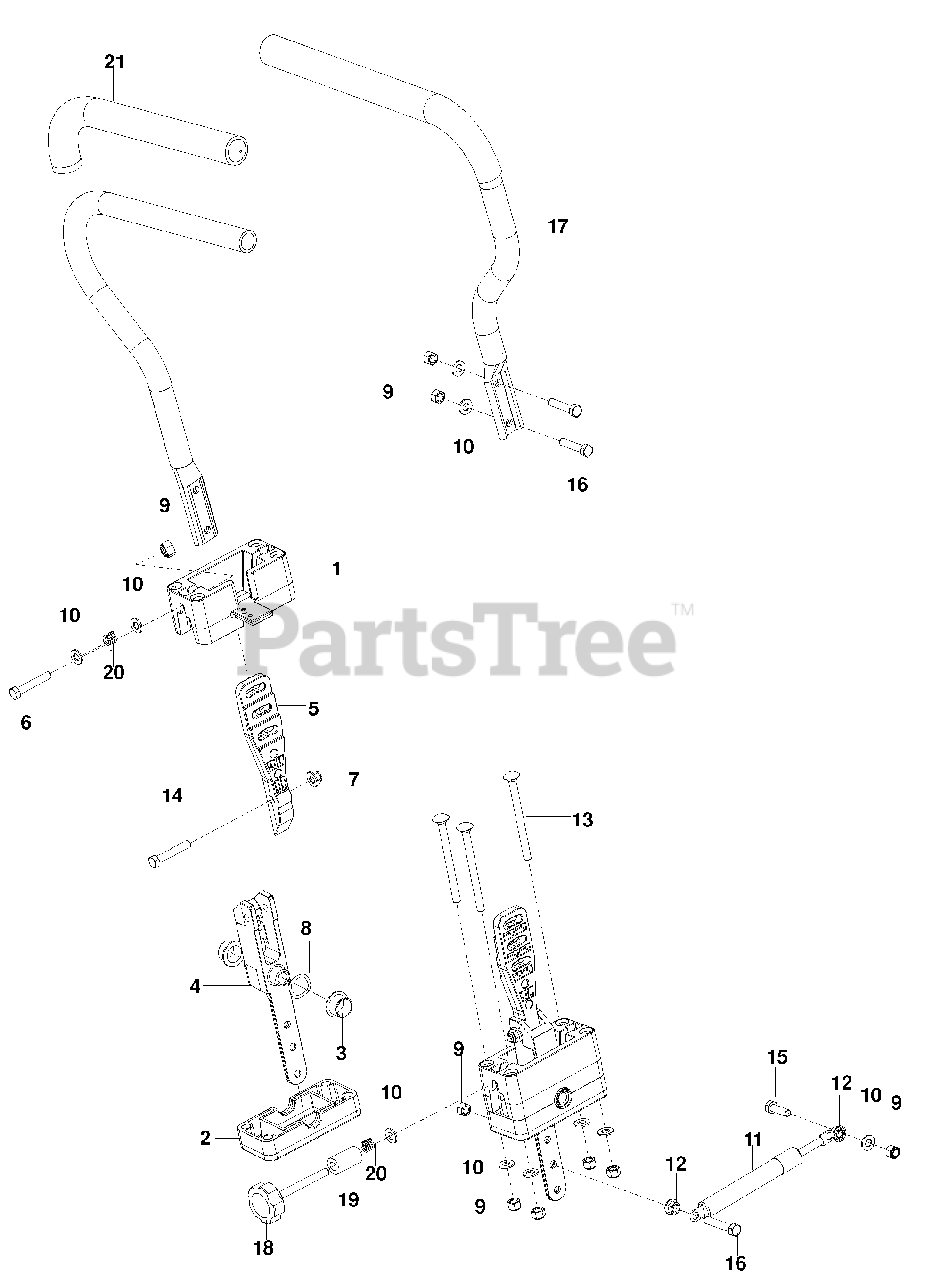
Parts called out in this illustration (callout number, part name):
1	BLOCK, UPPER
2	BLOCK, LOWER
3	BEARING, FLANGE
4	PIVOT SECTION, DRIVE
5	MOUNT, DRIVE CONTROL
6	HCS 5/16-18 x 2 TPBLT
7	NUT 5/16-18 FLANGE NYLOC
8	WASHER, .825 x 1.087 WAVE
9	NUT 5/16-18 HEX NYLOC
10	WASHER 5/16 SAE FLT
12	NUT 5/16-18 HEX WHIZLK
13	RHSNB 5/16-18 x 4
14	HCS 5/16-18 x 1 3/4
15	HCS 5/16-18 x 1
16	HCS 5/16-18 x 1 1/2
17	LEVER, w/GRIP
21	GRIP, FOAM
